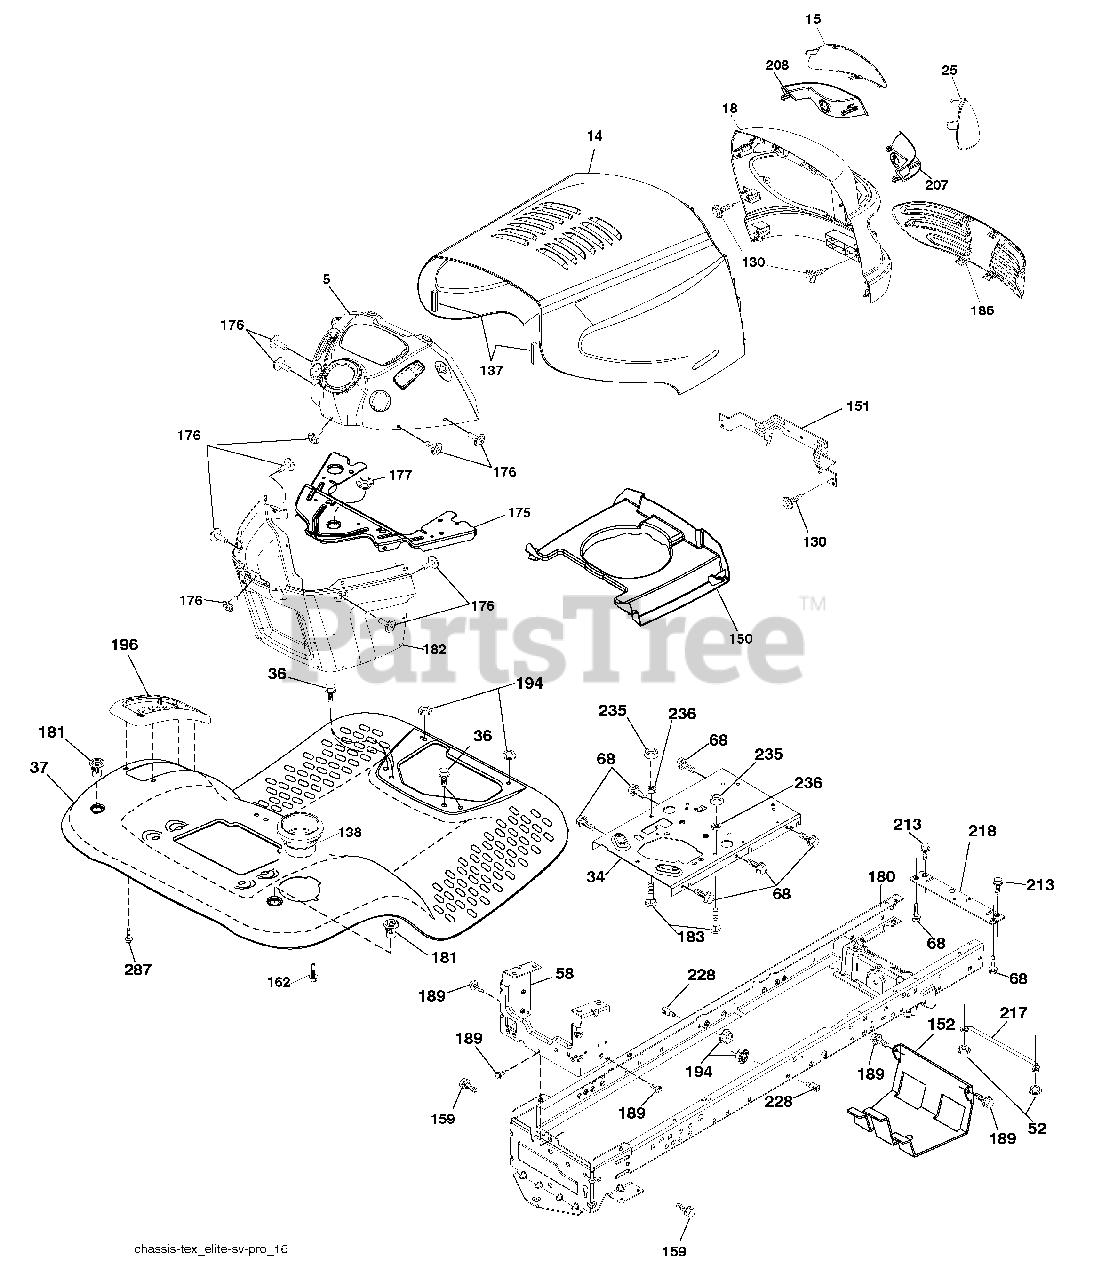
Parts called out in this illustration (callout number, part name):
5	Dash
14	Hood
15	Lens Grille LH
18	Grille
25	Lens Grille RH
34	Plate Engine
36	Screw 5/16-18 x 3/4
37	Fender
52	Nut Lock 5/16-18
58	Drawbar Upper
68	Screw Thdrol 5/16-18 x 1/2
130	Screw #10 x 0.750
137	Bumper Hood
138	Cupholder
150	Duct Heat Hood
151	Bracket Pivot
152	Shield Browning
159	Screw Hexwsh Thdrol 3/8-16 x 3/4
162	Screw Hex Wsh Hi-Lo 1/4 x 1/2
175	Crossmember
176	Screw 10-24 x 5/8 Wshd Qdrx
177	Bushing Steering
180	Chassis
181	Bushing Mtg. Fender Crgo.
182	Dash Lower
183	Bolt 5/16-18 x 1-1/4
189	Screw 5/16-18 x 3/4
194	Nut Lock Hex Flange 5/16-18
196	Console Asm. Deck Lift
207	Bezel Grille RH
208	Bezel Grille LH
213	Bolt 5/16-18 x 3/4
217	Rod Pivot Hood
218	X-Piece Hood Step
228	Stud Fastener
235	Spacer Fender
236	Nut Center Lock 5/16-18
287	Screw 1/4-20 x 3/8
